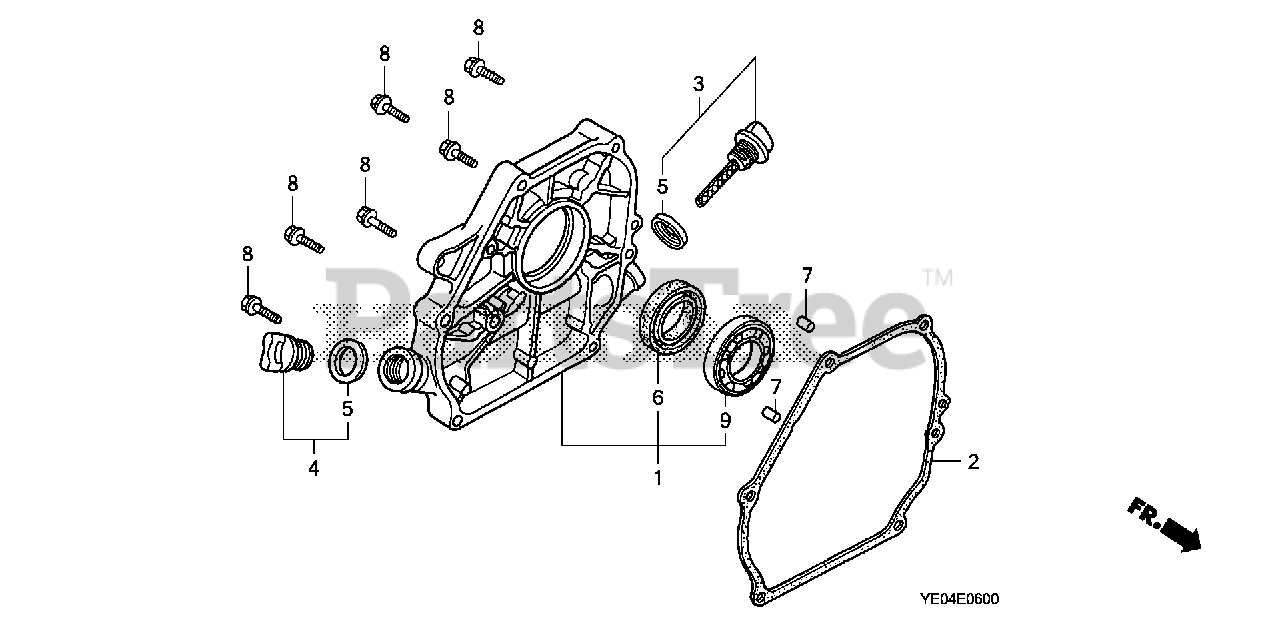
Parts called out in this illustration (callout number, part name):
1	COVER ASSY., CRANKCASE
2	GASKET, CASE COVER (NON-ASBESTOS)
3	CAP ASSY., OIL FILLER
4	CAP ASSY., OIL FILLER
5	GASKET, OIL FILLER CAP
6	OIL SEAL (25X41X6)
7	PIN A, DOWEL (8X14)
8	BOLT, FLANGE (8X32)
9	BEARING, RADIAL BALL (6205)
